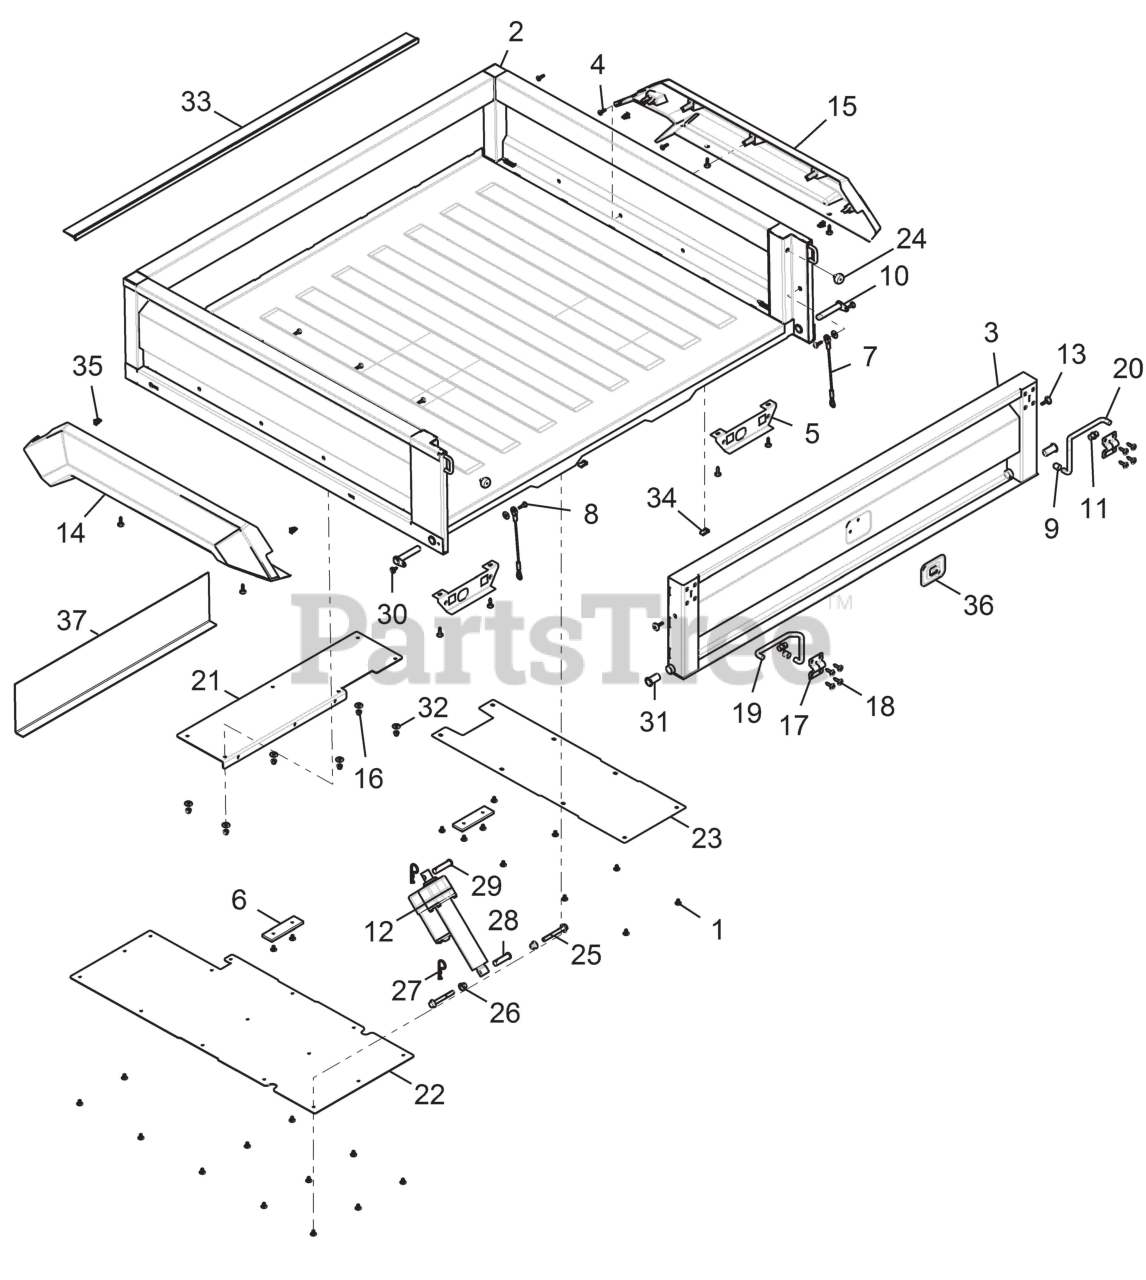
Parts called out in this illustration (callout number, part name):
1	RIVET(50) *
2	BOX, ARNS,GRAVELY RED
3	TAILGATE,ARNS,GRVLY RED
4	SCR-TXPH-#14 X .75 HI-LO RIE
5	BRKT.,TAILLIGHT MOUNT,RED
6	BUMPER-BOX BASE
7	TAILGATE CABLE
8	BLT-SHLDR .188X.188X.25-20
9	CAP, TAILGATE LATCH
10	PIN-TAILGATE MOUNT
11	BUSHING, TAILGATE LATCH
12	ACTUATOR, BOX LIFT
12	ACTUATOR-BOX LIFT,SPLY
13	SCR-TXTH-M6X1.0X25 RIE,SHDR
14	FLARE-BOX,LH,ARIENS
15	FLARE-BOX,RH,ARIENS
16	NUT-M6 FLANGE,NYLOK
17	BRKT-TAILGATE LATCH
18	SCR-TXTH-M6X1.0X25 RIE
19	ROD, LATCH, LH
20	ROD, LATCH, RH
21	SHIELD, HEAT, EXHAUST, FRONT
21	SHIELD, FRONT EXHAUST HEAT
22	SHIELD, HEAT, EXHAUST, REAR
22	SHIELD, REAR EXHAUST HEAT
23	SHIELD, HEAT EXHAUST MID
24	BUMPER, TAILGATE
25	SCR-HXFL-M10X1.25X80 8.8 ZOD
26	NUT-M10X1.25,FLG,NYLOC-OLIVE D
27	CLIP, HITCH PIN
28	PIN, CLEVIS
29	PIN, CLEVIS BOX LIFT 2"
30	SCR-M6X1X16 TR/TX-M
31	BUSHING, TAILGATE PIVOT PIN
33	TRIM,BOX
34	CLIP-U SPEED NUT
35	CLIP, DASH TRIM METAL
37	SHIELD, BED HEAT FOIL
